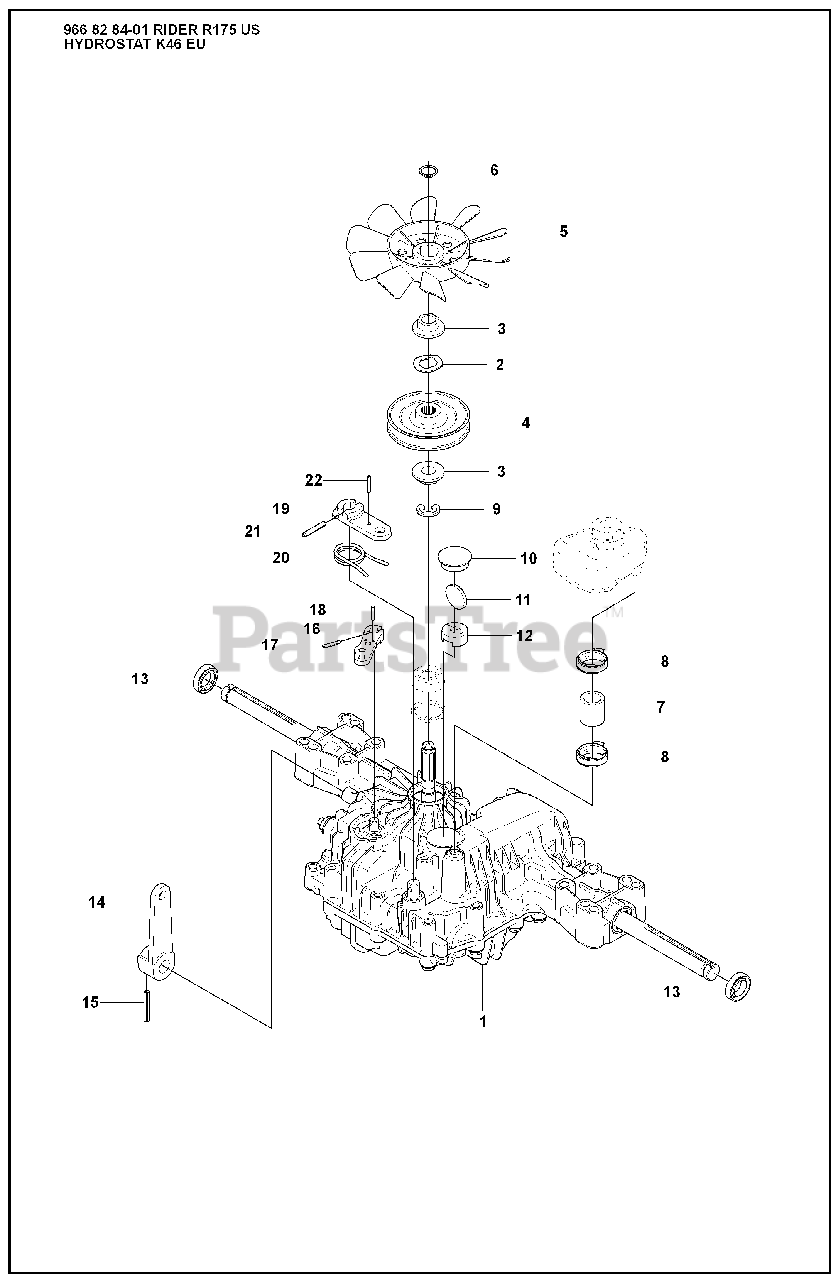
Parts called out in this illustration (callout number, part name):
1	HYDROSTAT 7A646024070
5	FAN.BLACK.1A646083070
6	RETAINING RING **
8	CLAMP
12	MAGNET HOLDER
13	RP SEAL.19, 19216334280
14	CONTROL LEVER
20	RETURN SPRING
